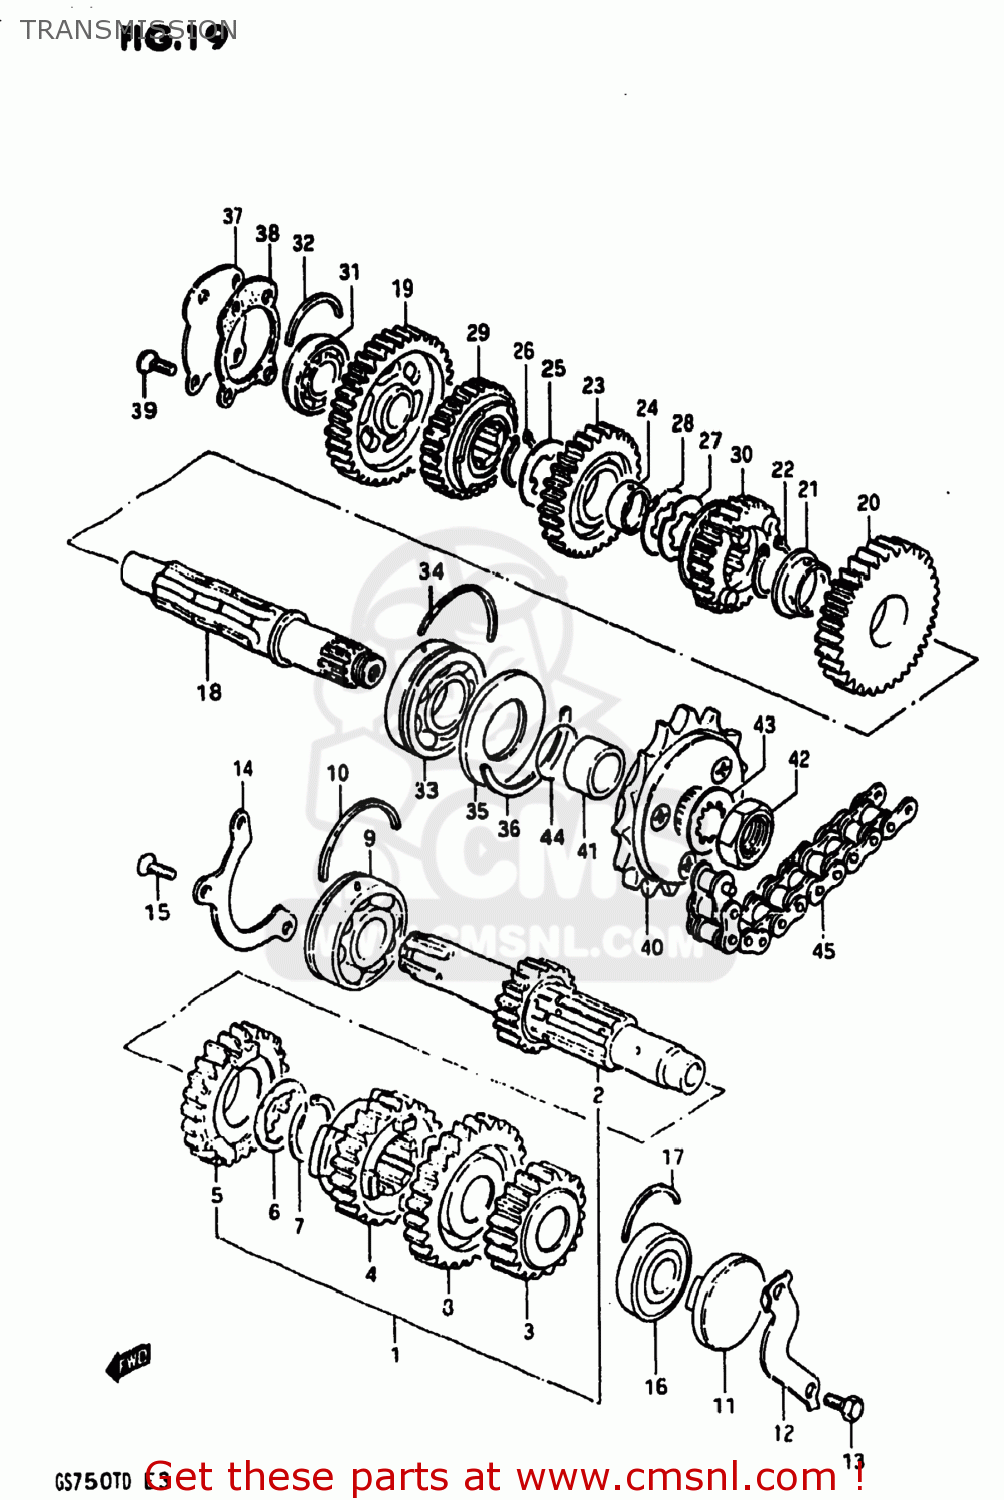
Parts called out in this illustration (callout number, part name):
1	SHAFT ASSEMBLY,COUNTER
2	SHAFT,COUNTER
3	GEAR,SECOND DRIVE
4	GEAR,THIRD DRIVE
5	GEAR,FOURTH DRIVE
6	WASHER,LOCK
7	CIRCLIP
8	GEAR,FIFTH DRIVE
9	BEARING(25X62X17)
10	C-RING
11	PLUG
12	RETAINER,CL PUSH ROD OIL SEAL
13	BOLT
14	RETAINER,CNTR SHAFT BEARING
15	SCREW
16	BEARING(20X47X14)
17	C RING
18	SHAFT,DRIVE
19	GEAR,FIRST DRIVEN
20	GEAR,SECOND DRIVEN
21	BUSH(28X32X2)
22	CIRCLIP
23	GEAR,THIRD DRIVEN
24	BUSH,3RD DRIVEN GEAR
25	WASHER,LOCK
26	CIRCLIP
27	WASHER,LOCK
28	WASHER
29	GEAR,FOURTH DRIVEN
30	GEAR,FIFTH DRIVEN
31	BEARING
32	C RING
33	BEARING(25X62X17)
34	C-RING
35	SEAL,OIL(32X62X7)
36	C RING
37	PLATE,DRIVE SHAFT
38	GASKET,DRIVESHAFT PLATE (MCA)
39	SCREW
40	SPROCKET,ENGINE
41	SPACER(25X32X18.6)
42	NUT
43	WASHER
44	O RING(D:1,ID:24.5)
45	CHAIN ASSEMBLY,DRIVE
